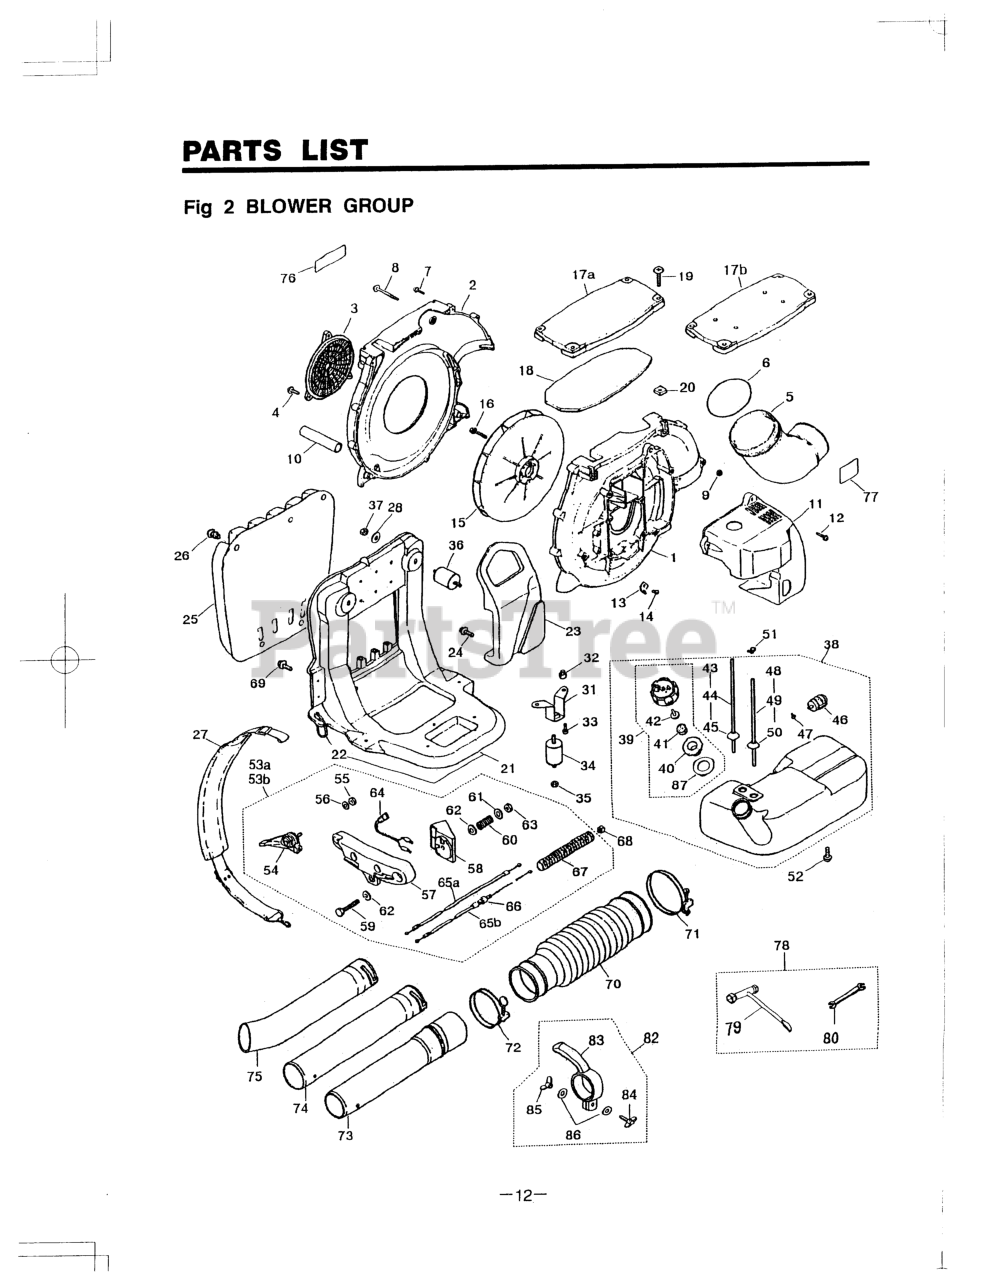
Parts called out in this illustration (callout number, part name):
1	CASE, VOLUTE
2	COVER, VOLUTE
3	NET, GUARD (RPLS-12222)
6	O-RING
7	SCREW
9	NUT (B)
11	COVER, ENGINE (RPLS-11210)
12	SCREW
15	FAN (REPLACES 3490-12110)
16	BOLT (RPLS 3405-12211)
17A	COVER (RPLS -13111)
18	COVER, PACKING
19	SCREW
20	NUT
22	RING (USE -21121)
23	HANGER (RPLS -21210)
25	PAD (RPLS -21310)
26	CLIP (RPLS 3490-21320)
28	WASHER, FLAT
31	BRACKET (RPLS -22510)
32	WASHER
33	SCREW, M5X20 (RPLS.1400-75510)
34	MOUNT (A) (RPLS 3490-22110)
35	NUT, M6 X 5
36	MOUNT (B) (RPLS 3405-22120)
37	NUT, M6 X 5
38	TANK ASSY (RPLS -23005)
39	CAP ASSY (RPLS -23202)
40	INNER CAP
43	PIPE (RPLS 3490-23410)
44	PIPE (USE 1696-85400)
45	GROMMET
46	FILTER ASSY
47	CLIP (REPLACES 2841-31280)
48	PIPE ASSEMBLY
49	PIPE (USE 1620-81710)
50	GROMMET
51	CLIP
52	SCREW, M5 x 12
53A	LEVER SET
54	LEVER, THROTTLE
55	NUT (B)
56	WASHER, M5x.8(RPLS 01624-20508
58	BRACKET
59	BOLT
60	SPRING
61	WASHER
62	WASHER, FLAT
63	NUT, M6 X 5
64	SWITCH, STOP
65A	CABLE, THROTTLE
67	TUBE (USE 5548-73310)
69	BOLT
70	HOSE, FLEXIBLE
71	2756-51510 (RPLS. 07280-09832)
73	JOINT, SWIVEL
74	PIPE, EXTENSION
75	PIPE, BENT
78	TOOL SET
80	SPANNER, 8 X 10 (RPLS 2540- )
82	BLOWER ASSIST HANDLE
83	EBH100
84	BOLT, WING
85	NUT, WING
86	WASHER
87	PACKING (RPLS -85321)
